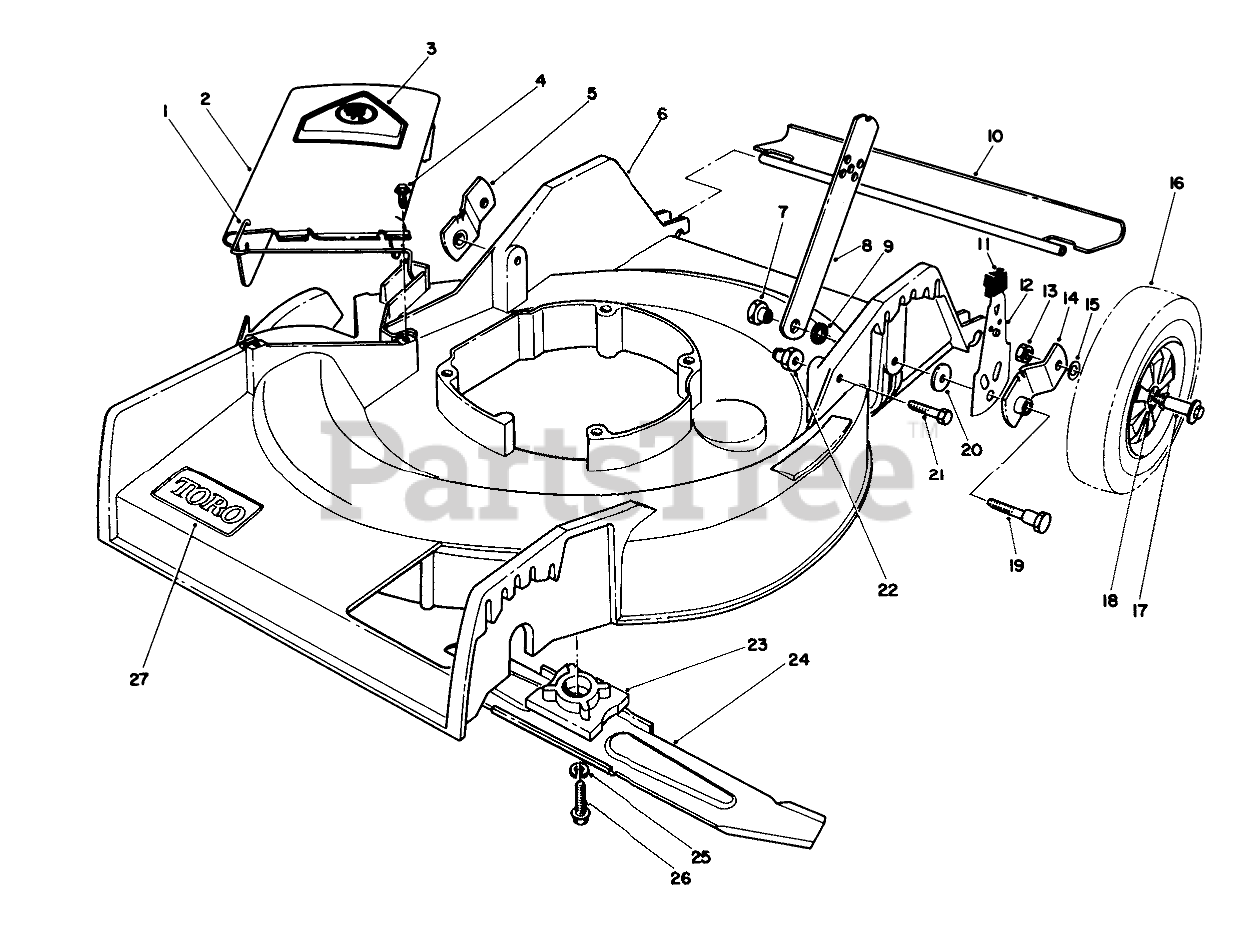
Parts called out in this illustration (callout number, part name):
1	SPRING HINGE
2	Deflector (Incl. Ref. #1 & 3)
3	DECAL-DANGER
4	SCREW-HWH
5	Pivot Arm
6	HOUSING W/DECAL
7	HANDLE PIVOT NUT
8	HANDLE LATCH
9	SPACER
10	SHIELD - TRAILING
11	KNOB-ARM
12	REAR SPRING ARM ASM
13	Nut
14	Pivot Arm
15	WASHER
16	Wheel & Tire Assembly (Incl. Ref. #18)
17	BOLT-WHEEL
18	BUSHING
19	PIVOT SCREW
20	PIVOT WASHER
21	SCREW-HH
22	HANDLE PIVOT NUT
23	BLADE RETAINER
24	Blade
25	WASHER-LOCK
26	SCREW-HH
27	DECAL
